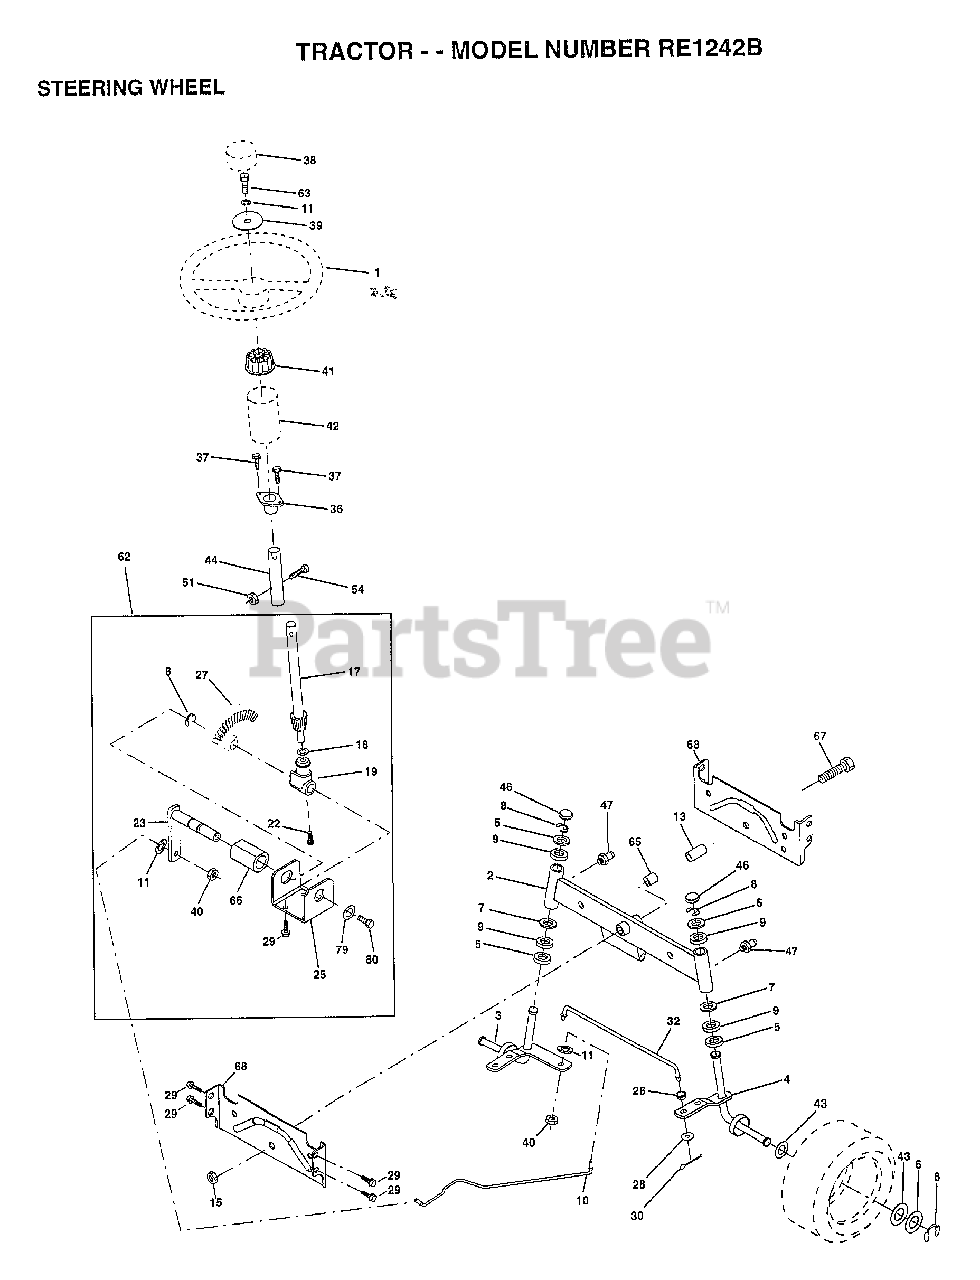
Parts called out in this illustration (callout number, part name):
2	AXLE ASM
3	SPINDLE.ASM.LH
4	"SPINDLE ASM,RH"
5	WASHER .T
6	WASHER
7	WASHER
8	RING
9	COL. SRTG. BEAR.
10	DRAGLINK-STAMPED
11	LOCKWASHER
13	BEARING AXLE
15	"NUT-LOC,FLANGE LT"
17	SHAFT ASM STEERIN
18	THRUST WASHER
19	SUPPORT.SHAFT.STEER
22	SCREW.HX.WSH.HD
23	SHAFT.ASM.PITMAN
25	BRKT-STEERING
26	BUSHING.DRAGLINK
27	GEAR SECTOR
28	WASHER
29	SCREW
30	COTTER PIN
32	TIE ROD
36	BUSHING.STEERING
37	"SCREW-TT,10-32 FL"
38	ST WHL INSERT CAP
39	WASHER T
40	GRIPCO NUT
41	ADAPTER LT
42	BOOT.STEER.PL
43	WASHER
44	EXT SHAFT STEERIN
46	CAP
47	ZERK M
51	NUT
54	BOLT
62	KIT.STEER.ASM
63	BOLT
65	SPACER AXLE
66	"BEARING-ARM,PITMA"
67	BOLT
68	BRACE AXLE
79	WASHER
80	BOLT.HX.NYLON3/8-16X3/
